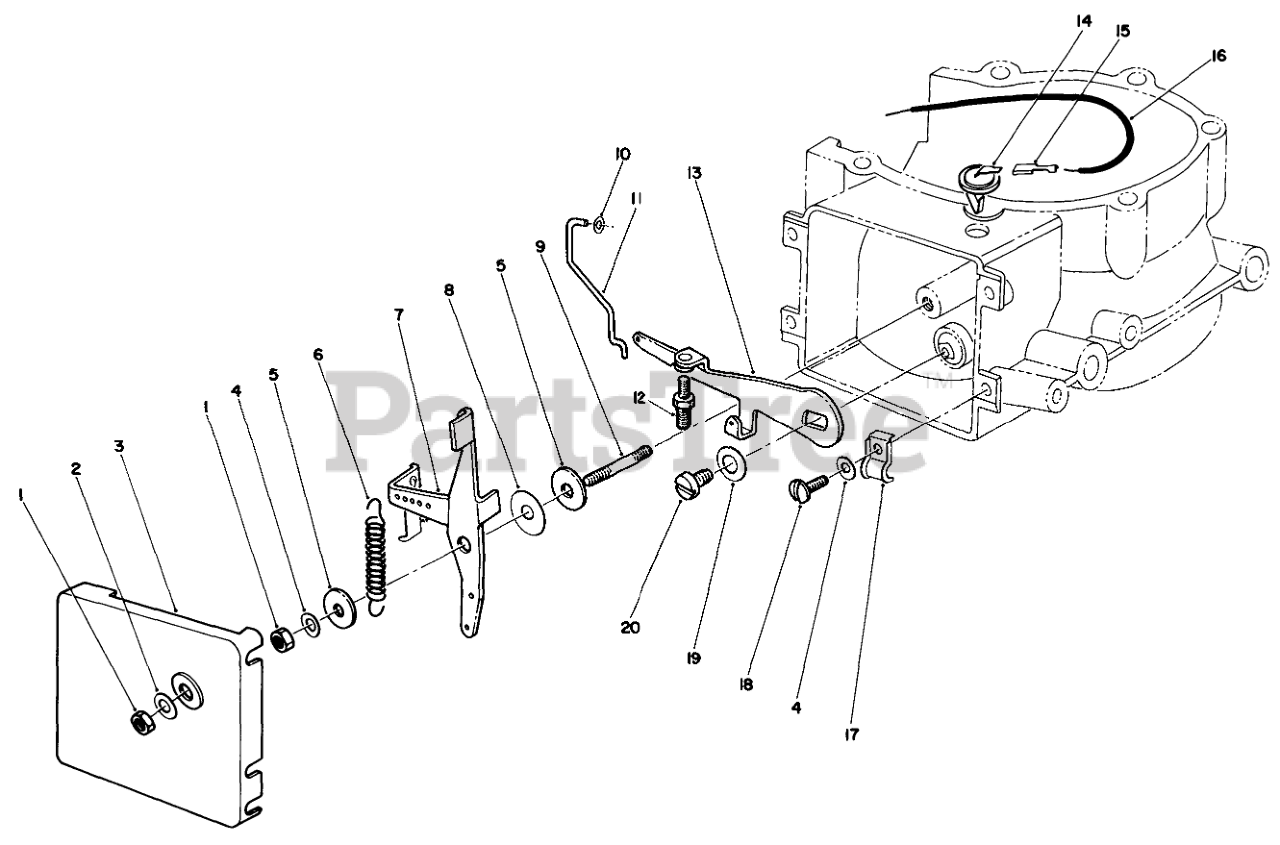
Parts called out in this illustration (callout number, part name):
2	Washer
3	Cover-Governor Housing
4	Washer-Spring
5	Washer
6	Spring
7	Lever
8	Disc-Brake
10	Washer-Tab
11	LINKAGE
12	Damping Spring Assembly
13	Lever
14	Connector Assembly
15	Connector-Spade
17	Clamp
18	Screw
19	Washer-Spring
20	Screw
